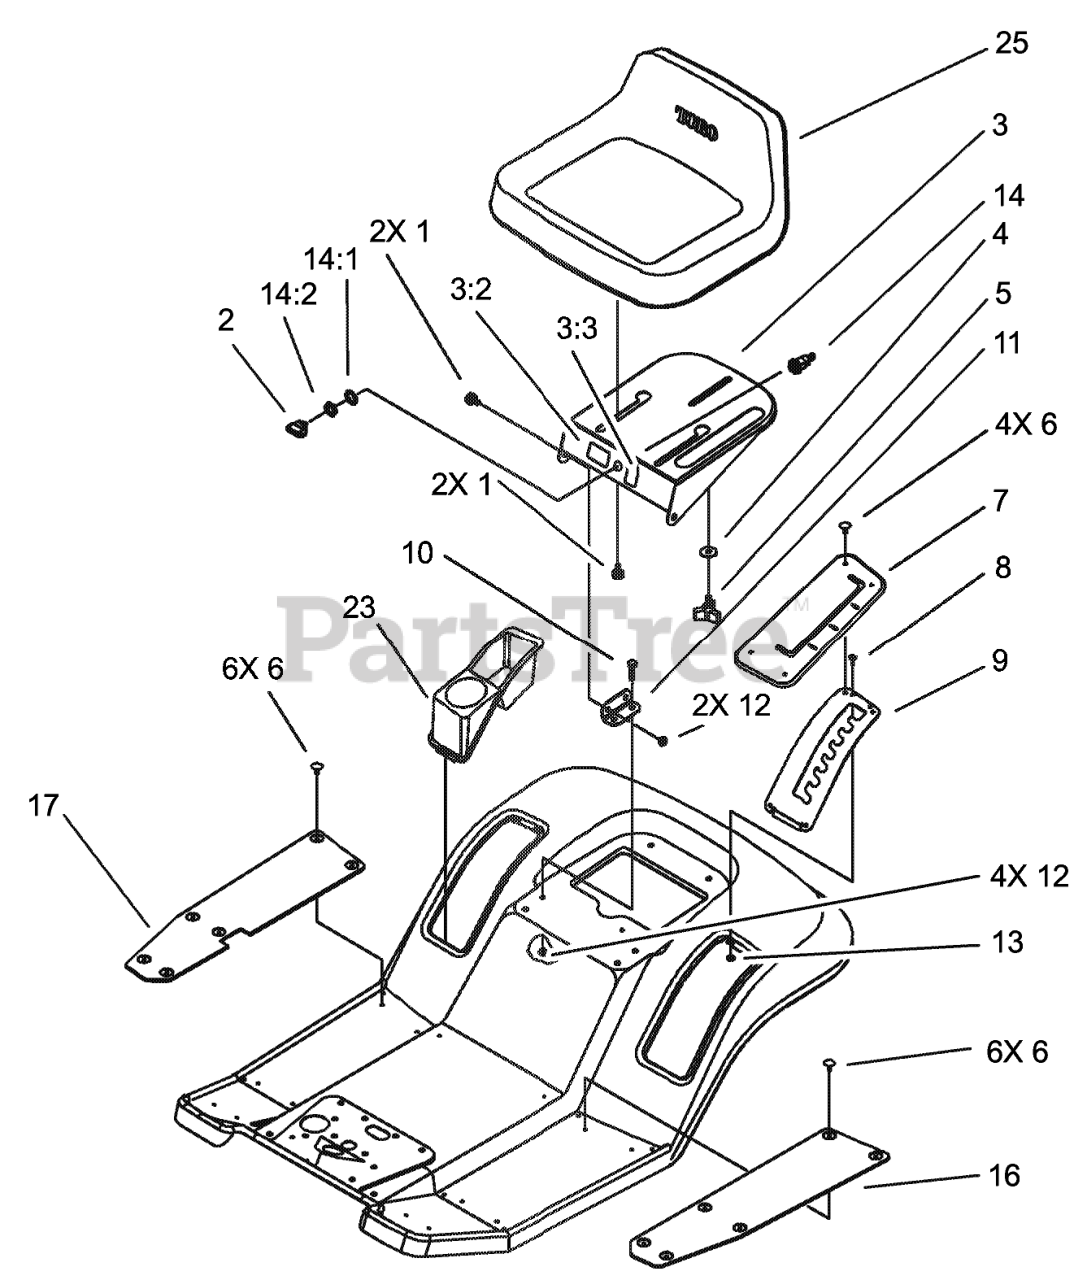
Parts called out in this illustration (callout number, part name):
1	BOLT-SHOULDER
2	KEY-IGNITION
3	SEAT SUPPORT ASM
3:2	DECAL-DANGER
3:3	DECAL-SWITCH
4	WASHER-PIVOT
6	FASTENER-PANEL
7	COVER-HOC
8	RIVET-BLIND
9	GATE-HOC
10	SCREW-HH
11	BRACKET-PIVOT, SEAT
12	NUT-LOCK, NI
13	WASHER-PLAIN
14	STARTER SWITCH ASM
14:1	WASHER-TOOTH, INTERNAL
14:2	NUT-HH
16	MAT-FOOT, LH
17	MAT-FOOT, RH
23	TRAY-FENDER
25	SEAT-V-511
